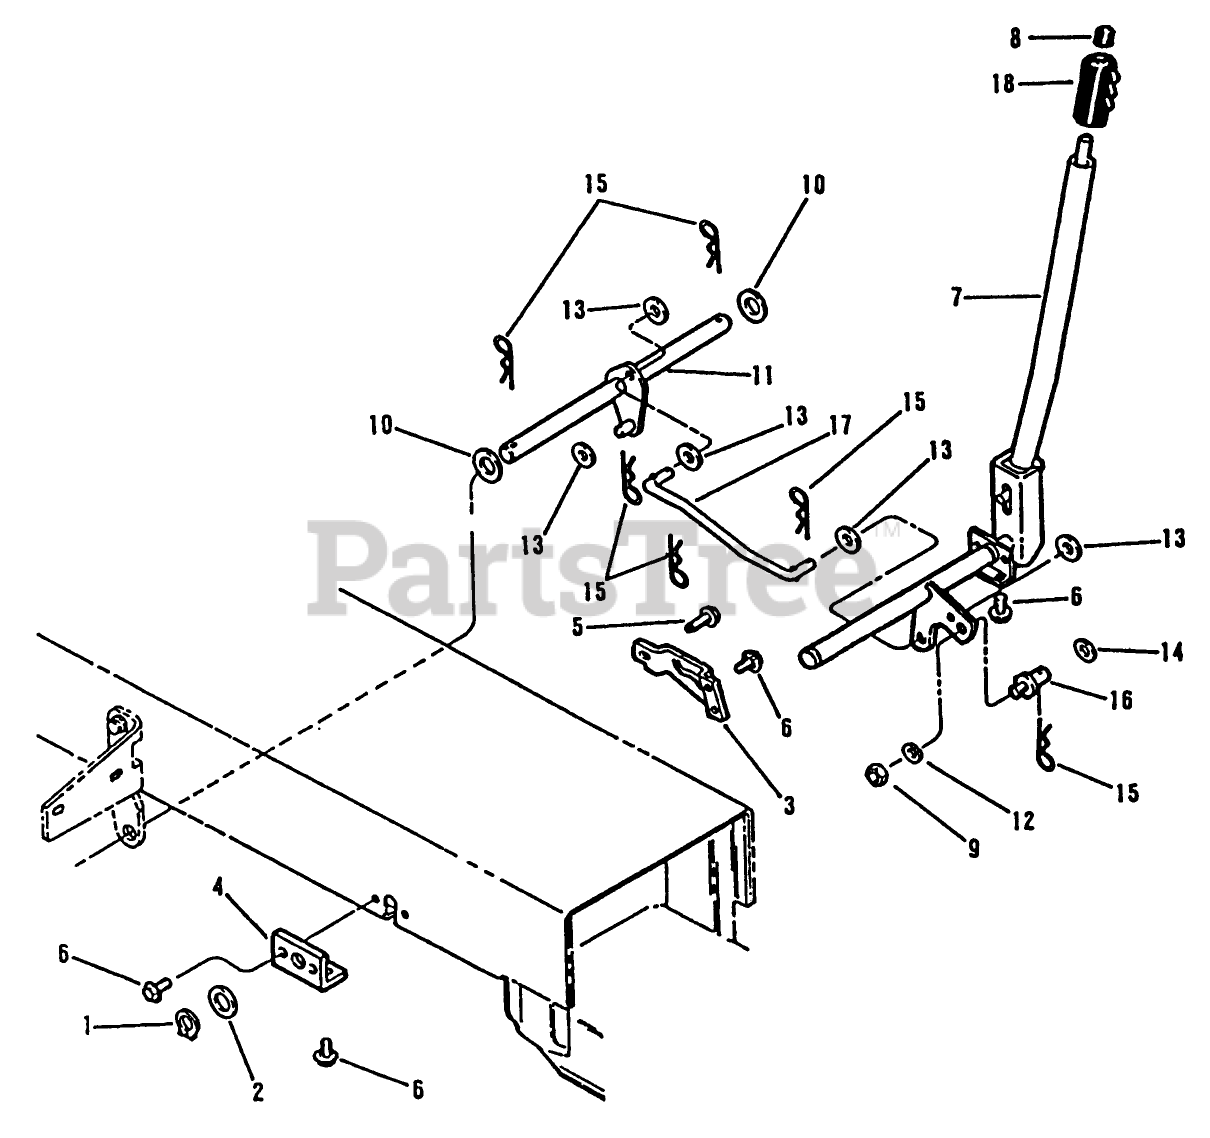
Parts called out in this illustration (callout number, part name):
1	RING-RETAINING
2	WASHER
5	SCREW
8	TIP-ROD
9	NUT
12	WASHER
13	WASHER
15	PIN-HAIR
